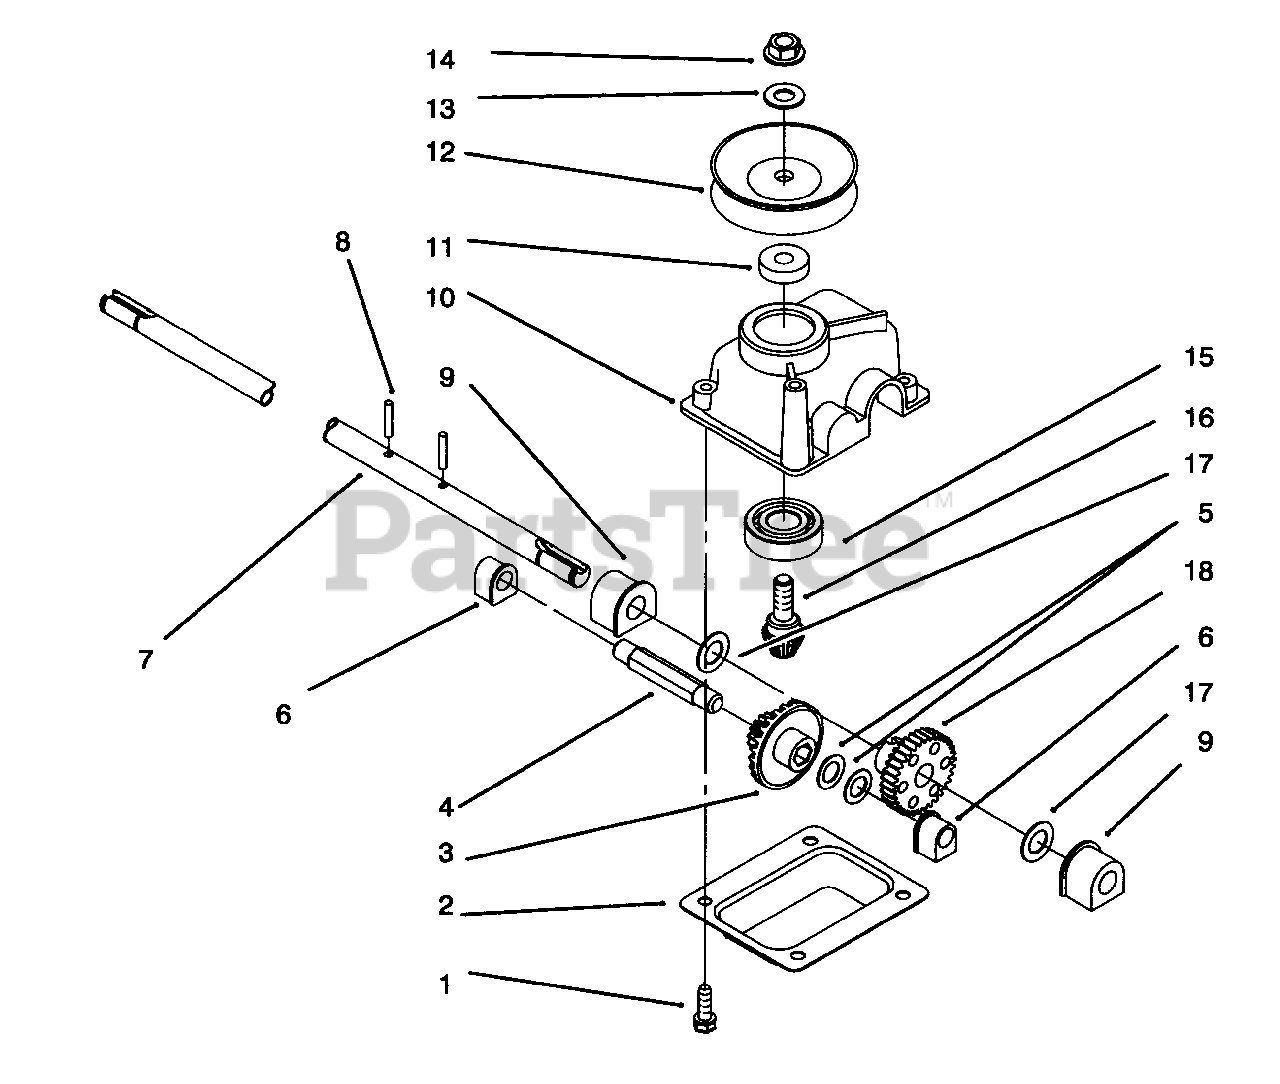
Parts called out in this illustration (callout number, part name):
1	Screw-Taptite
2	Cover-Gear Case
3	Pinion-15 Tooth
4	Shaft-Intermediate
7	Shaft-Output
8	Pin-Groove
9	Bushing-Output
10	Gearcase
12	Pulley-Half
15	Bearing-Ball
16	Gear-Bevel Pinion
17	Washer-Thrust
18	Gear 34 Tooth
